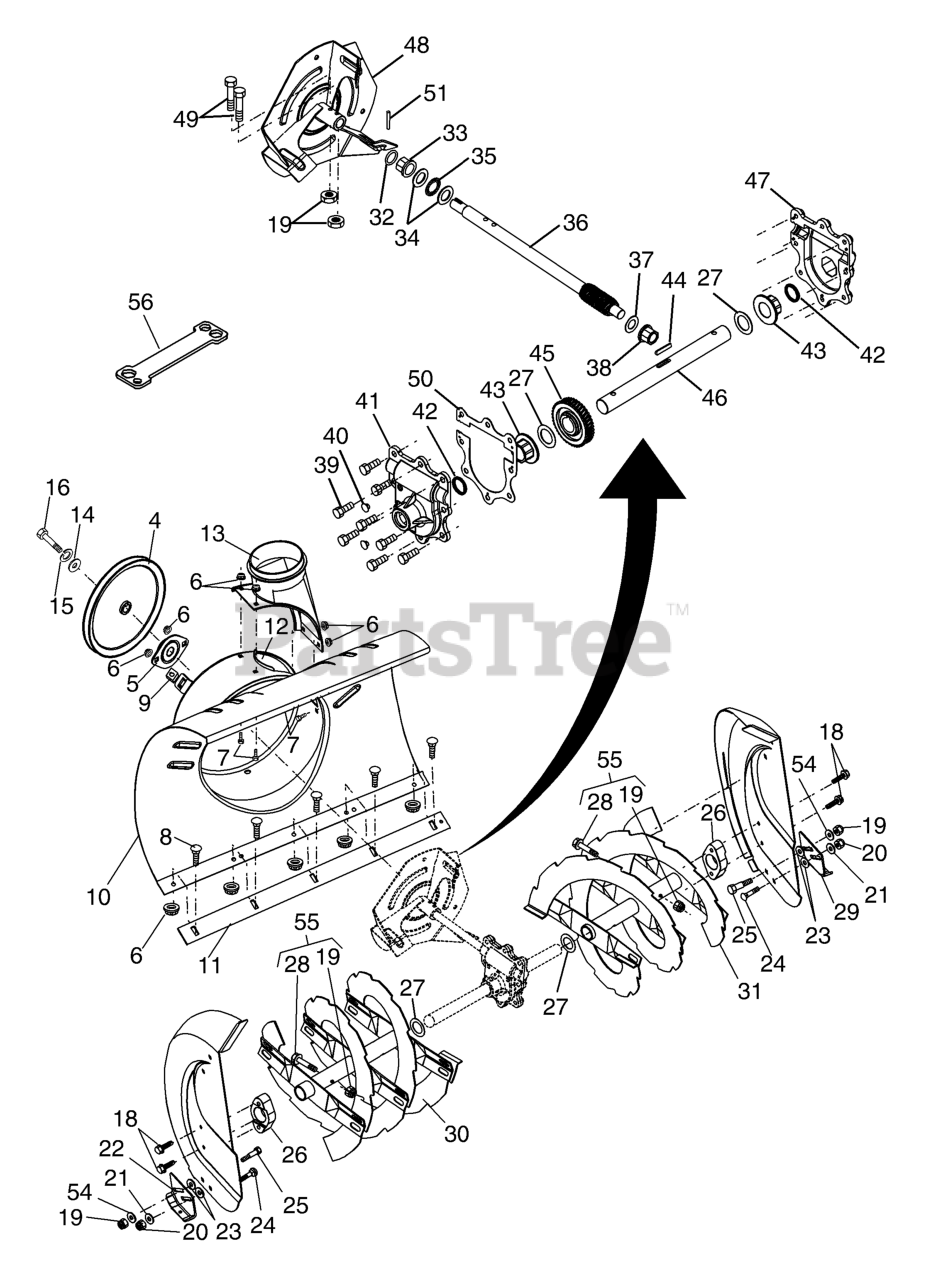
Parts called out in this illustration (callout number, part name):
4	PULLEY, IMPELLER
5	BEARING FLANGE
6	NUT.FLANGE.5/16
7	BOLT.CARRIAGE.5/16-18X
8	BOLT
9	NUT, CAGE 3/8-16
10	RP HOUSING, AUGER 24"
11	BAR, SCRAPER 24"
12	BRACKET, CORNER DISCHARGE
13	BASE DISCHARGE CHUTE
14	WASHER, FLAT
15	WASHER.LOCK.HVY.HLCL.SPR.5/16
16	Screw, Hex Head 5/16-18 x 3/4
18	SCREW, HEX HD 5/16X1
19	LOCKNUT.NYLOC.1/4-20
20	NUT.71038.31-18.HEX.NYLOCK
21	WASHER.20X8.5
22	SKID PLATE RH
23	WASHER, NYLON FRICTION
24	BOLT
25	SHOULDER BOLT
26	BEARING, AUGER
27	WASHER TRUST 1"
28	BOLT.SHOULDER.SHEAR.1/4-20.
29	SKID PLATE LH
30	AUGER.WLDMNT.RH.24.PNT.STD
31	AUGER.WLDMNT.LH.24.PNT.STD
33	BUSHING FLANGE 3/4
34	WASHER, THRUST 3/4
35	BEARING TRUST 3/4 NTA-1220
36	SHAFT, IMPELLER
37	WASHER, THRUST 5/8
38	BUSHING.FLANGE.(.625X.75)
39	SELF-TAPPING SCREW 5/16-18X3/4
40	PLUG.AUGER.GEAR.BOX.SNOW
41	HOUSING.GEARBOX.RH.SNOW
43	BUSHING FLANGE 1"
44	KEY, SQUARE 1/4 X .875
45	WORM GEAR
46	SHAFT, AUGER
47	LH GEARBOX HOUSING
48	IMPELLER ASSY
49	SCREW.HEX.HD1/4-20X
50	GASKET.AUGER.GEARBOX
51	PIN, ROLL 3/16 X 1-1/8
54	WASHER
55	KIT, BOLT, SHEAR
56	RP WRENCH, SNOWTHROWER
